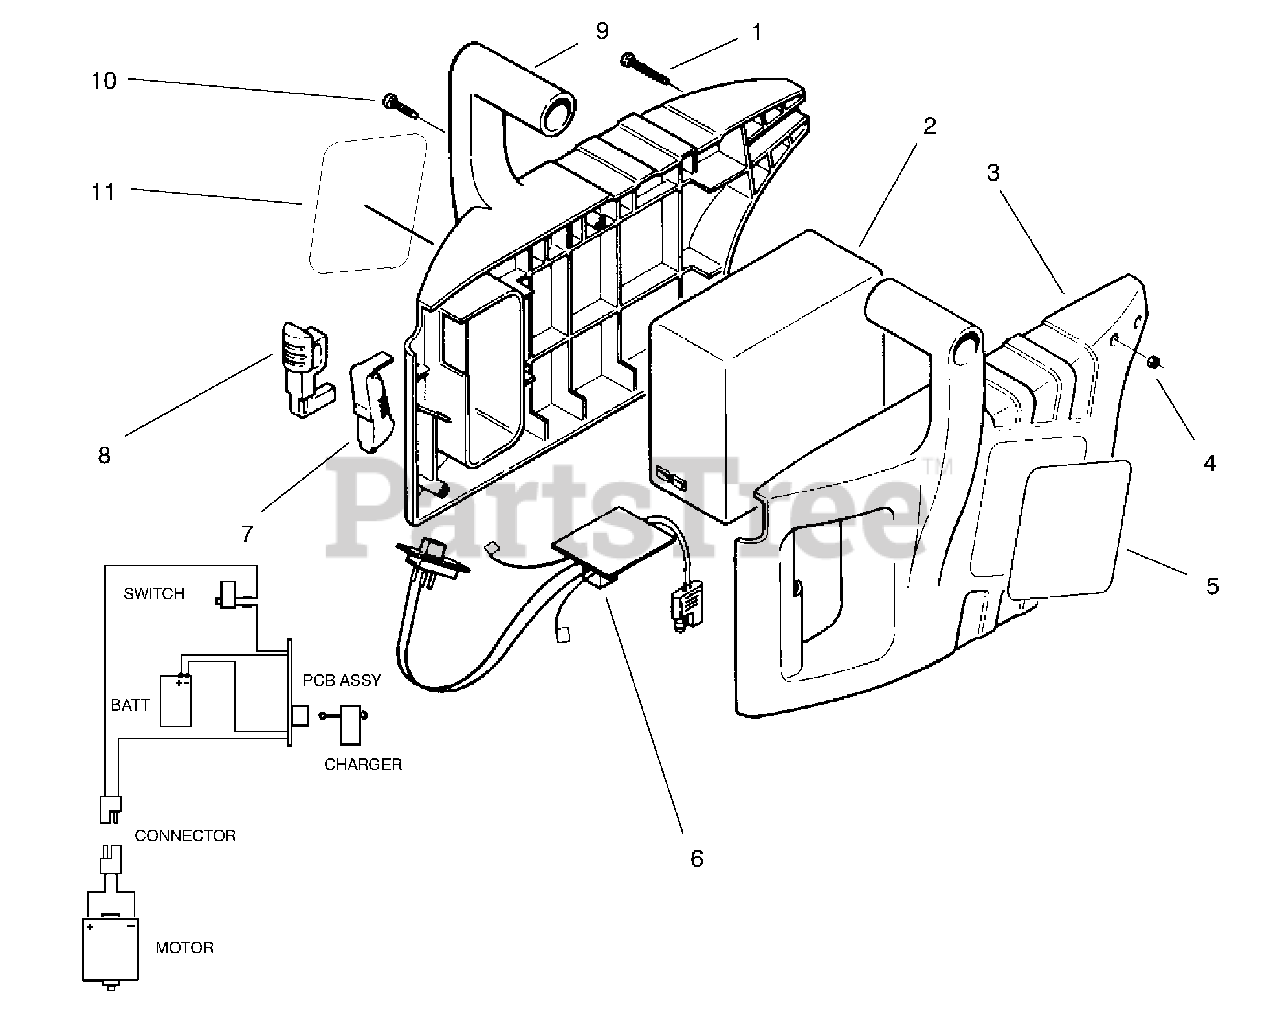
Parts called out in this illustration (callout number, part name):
1	Screw-Self Tapping
3	Handle & Battery Case R.H.
5	Decal-Toro
6	PCB Assembly
8	Lock-Trigger
9	Handle & Battery Case L.H.
11	Decal-Warning
